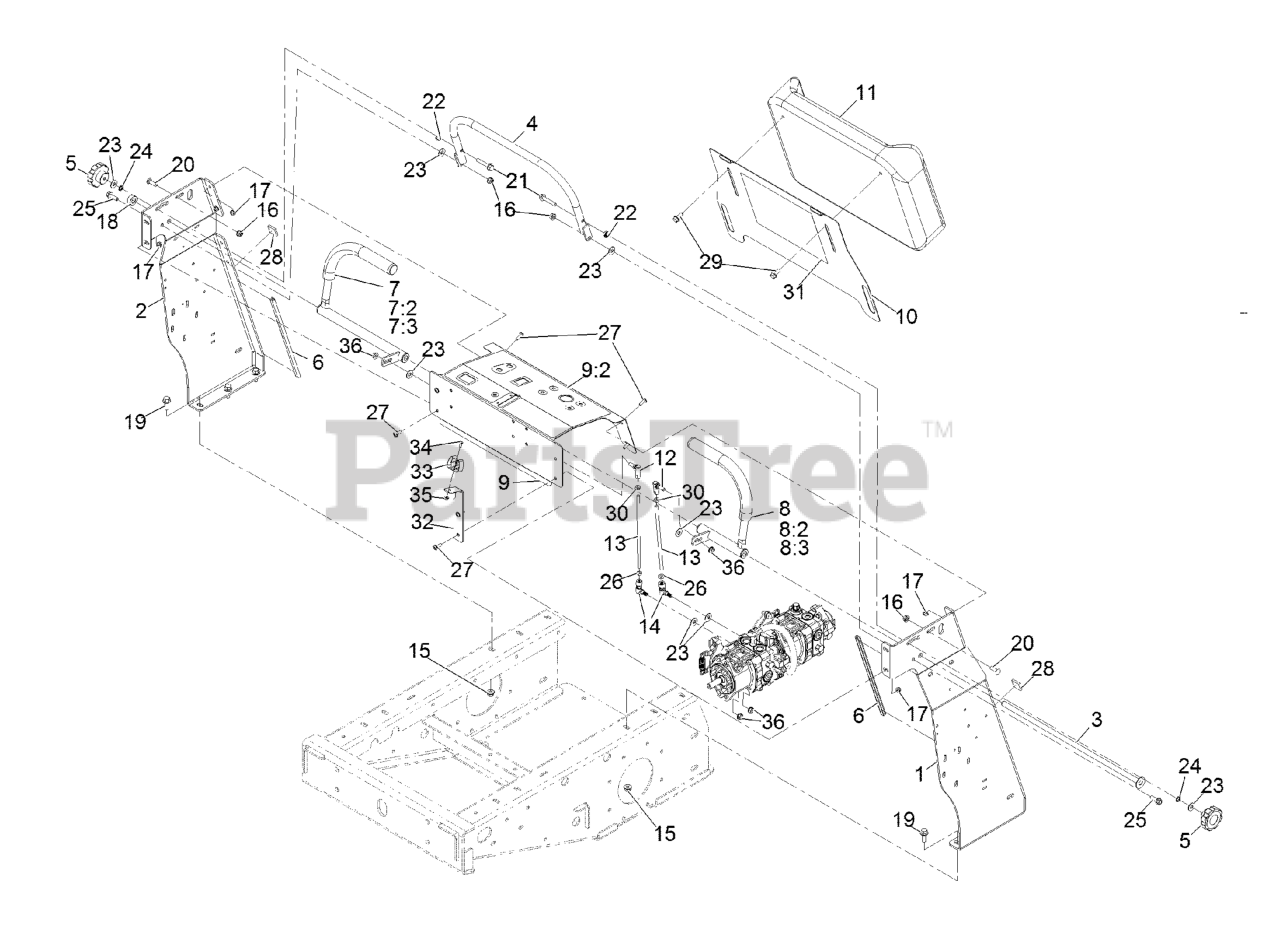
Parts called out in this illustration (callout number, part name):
1	Upright-Tower, Lt
2	Upright-Tower, Rt
3	Rod-Pivot, Joy Stick
4	Bar-Speed
5	KNOB-FLUTED
6	STRIP-TRIM, 12.0"
7	Stick-Joy, Rt
7:2	GRIP-CONTROL, MOTION
7:3	BUSHING-FLANGE
8	Stick-Joy, Lt
8:2	GRIP-CONTROL, MOTION
8:3	BUSHING-FLANGE
9	Panel-Control
9:2	DECAL-CONTROL PANEL
10	PLATE, KNEE PAD
11	Pad-Knee, Z-Spray/Z-Plug
12	Balljoint-SS
13	ROD-CONTROL, MOTION
14	Ball Joint-Quick Disconnect, SS
15	Nut-Hex Flange
16	Nut-Hex Flange
17	Nut-Hex Flange
19	SCREW-HHF
20	Bolt,Carriage,5/16-18X1,ST/ST 18-8
21	Screw-HHF
22	Nut,Hex Flange,5/16-18,Sst, Rie2006
23	FLAT WASHER, 5/16 NOM,ST
24	Washer-Lock
25	SCREW-HHF
26	Nut-Hex
27	Screw-Hsbhf
29	SCREW-HHF
30	Nut-Hex
31	DECAL-SPRAY CHART
32	Mount-Gun
33	Holder-Tool, Clip
34	Screw-HSBH
35	Nut-Hex Flange
36	Nut-HHF
